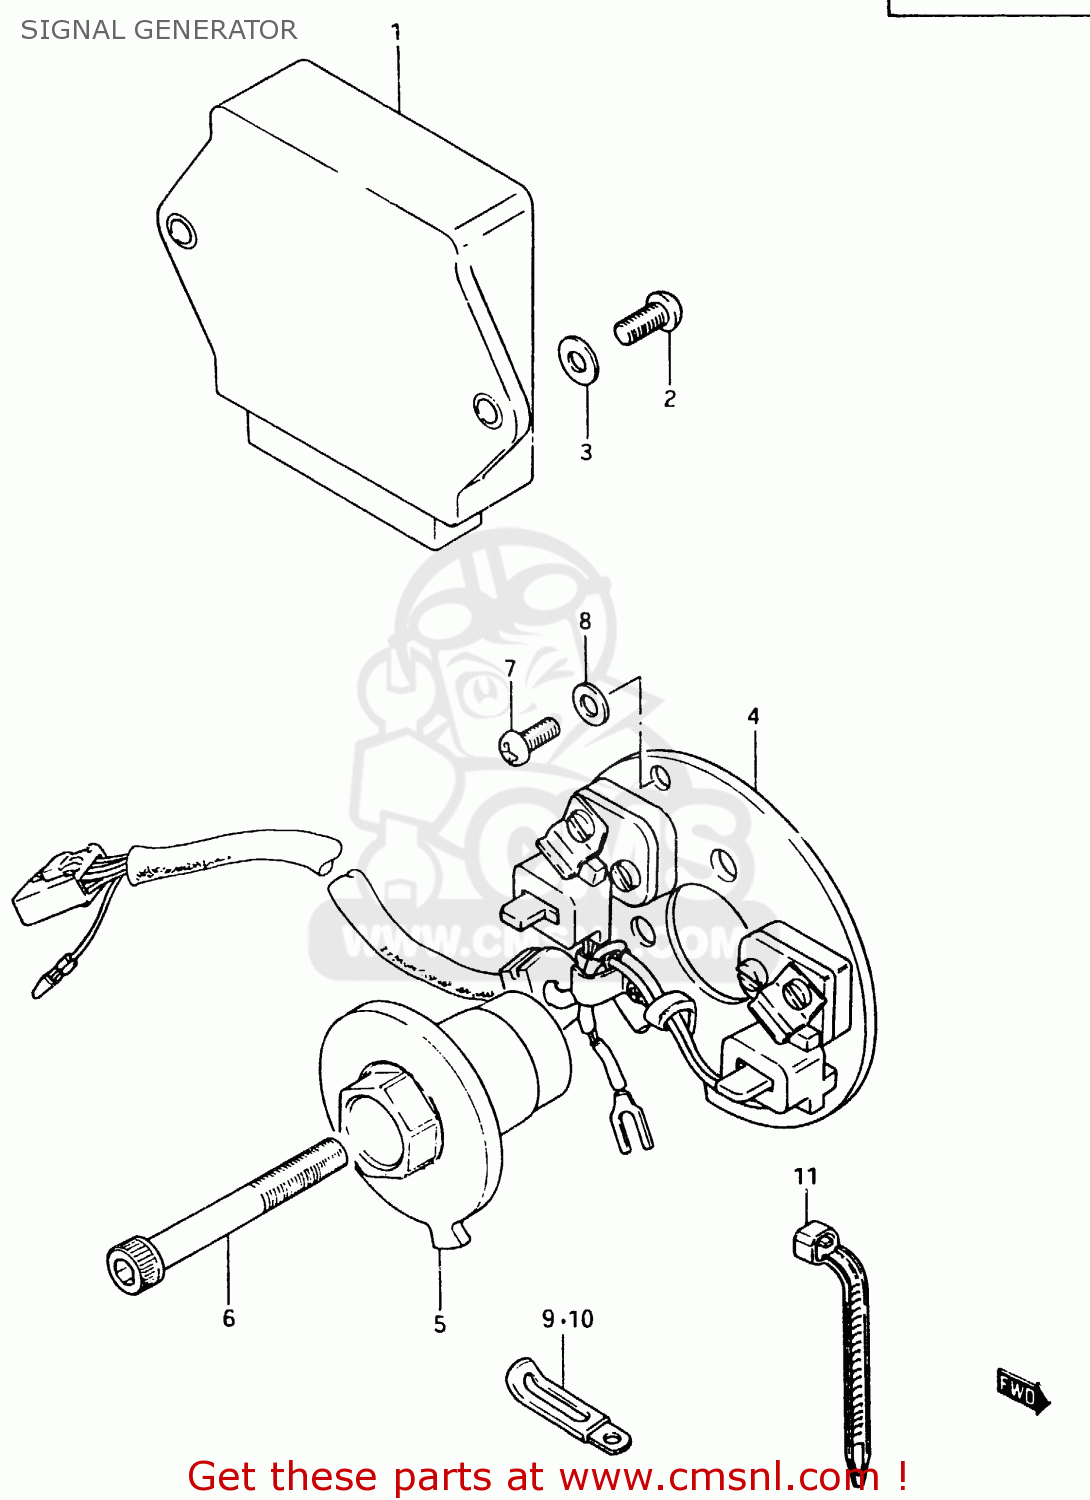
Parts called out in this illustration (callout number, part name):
1	IGNITER UNIT ASSEMBLY
2	SCREW
3	WASHER, LOWER
4	STATOR,SIGNAL GENERATOR
5	ROTOR,SIGNAL
6	BOLT
7	SCREW(5X12)
8	WASHER
9	CLAMP
10	CLAMP
11	CLAMP(L:125)
